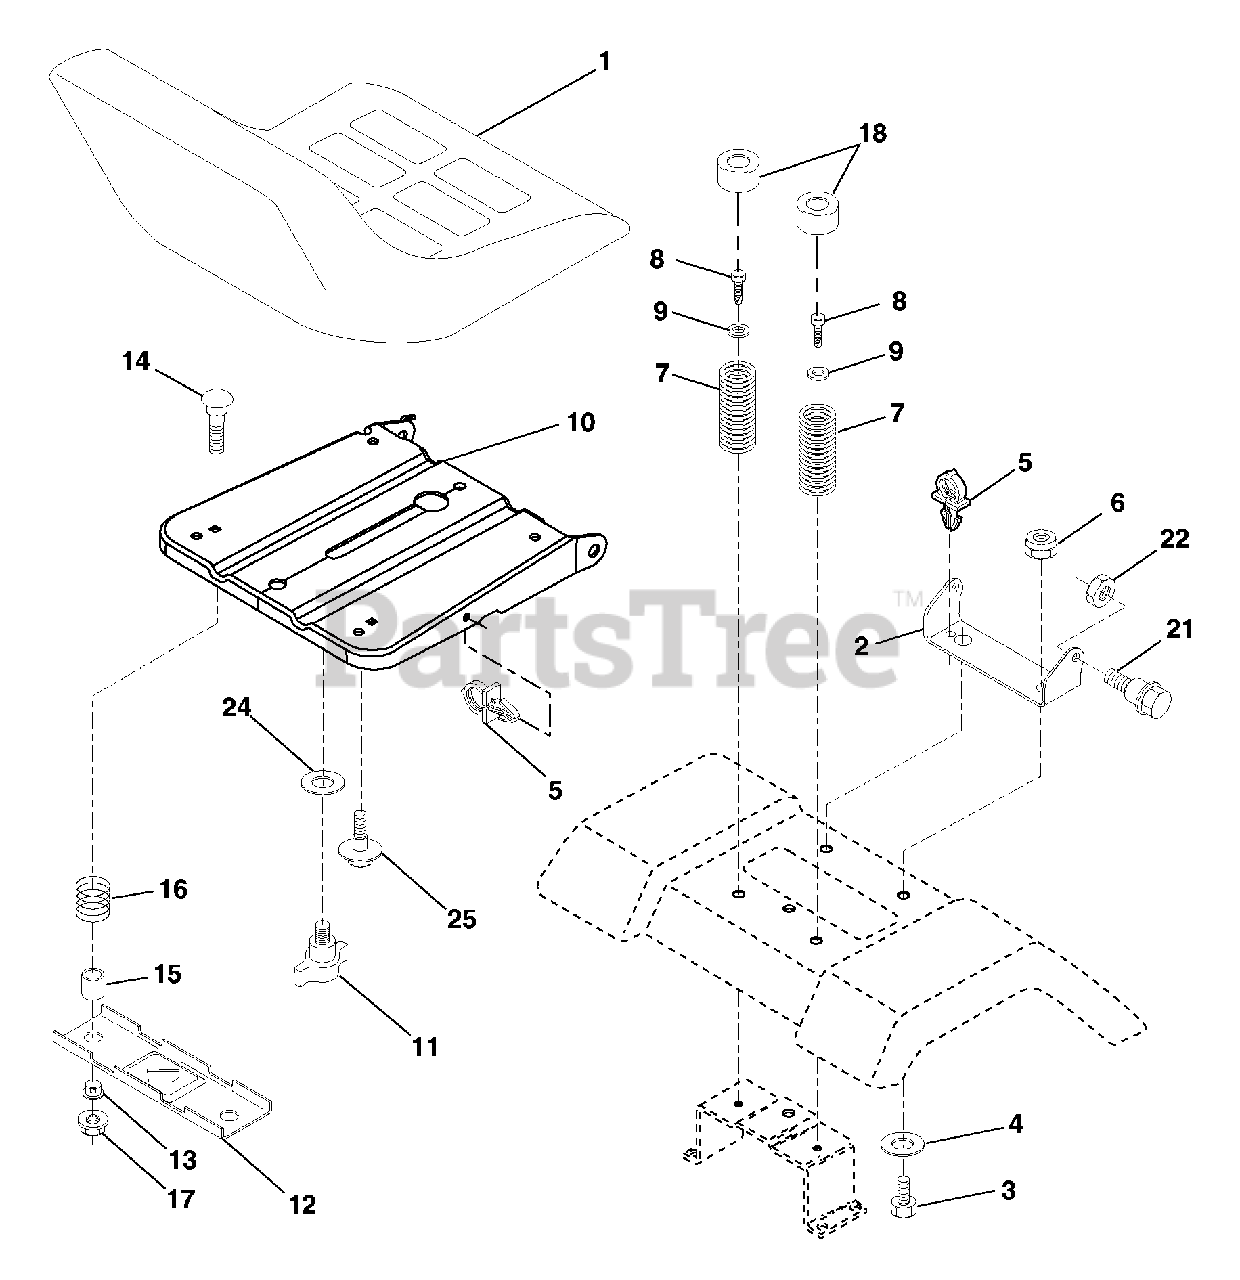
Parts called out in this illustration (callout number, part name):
1	Seat
2	Bracket Pivot Seat 8 720
3	Bolt Fin Hex 3/8-16 unc x 1
4	Washer Flat 13/32 x 1 x 10 Ga.
5	Clip Push-In
6	Nut Hex w/Ins. 3/8-16 unc
7	Spring Seat Cprsn 2 250 Blk Zi
8	Screw 3/8-16 x 1
9	Washer 13/32 x 1 x 14 Ga.
10	Pan Seat
11	Knob Seat
12	Bracket Mounting Switch
13	Bushing Snap Blk Nyl 50 Id
14	Bolt Rdhd Sqnk 1/4-20 x 1-1/2
15	Spacer Split
16	Spring Cprsn
17	Nut Lock 1/4 Lge Flg Gr. 5 Zinc
18	Cap Spring Seat
21	Bolt Shoulder 5/16-18 unc
22	Nut Hex
24	Washer 17/32 x 1-3/16 x 12 Ga.
25	Bolt Shoulder 5/16-18 x 62
